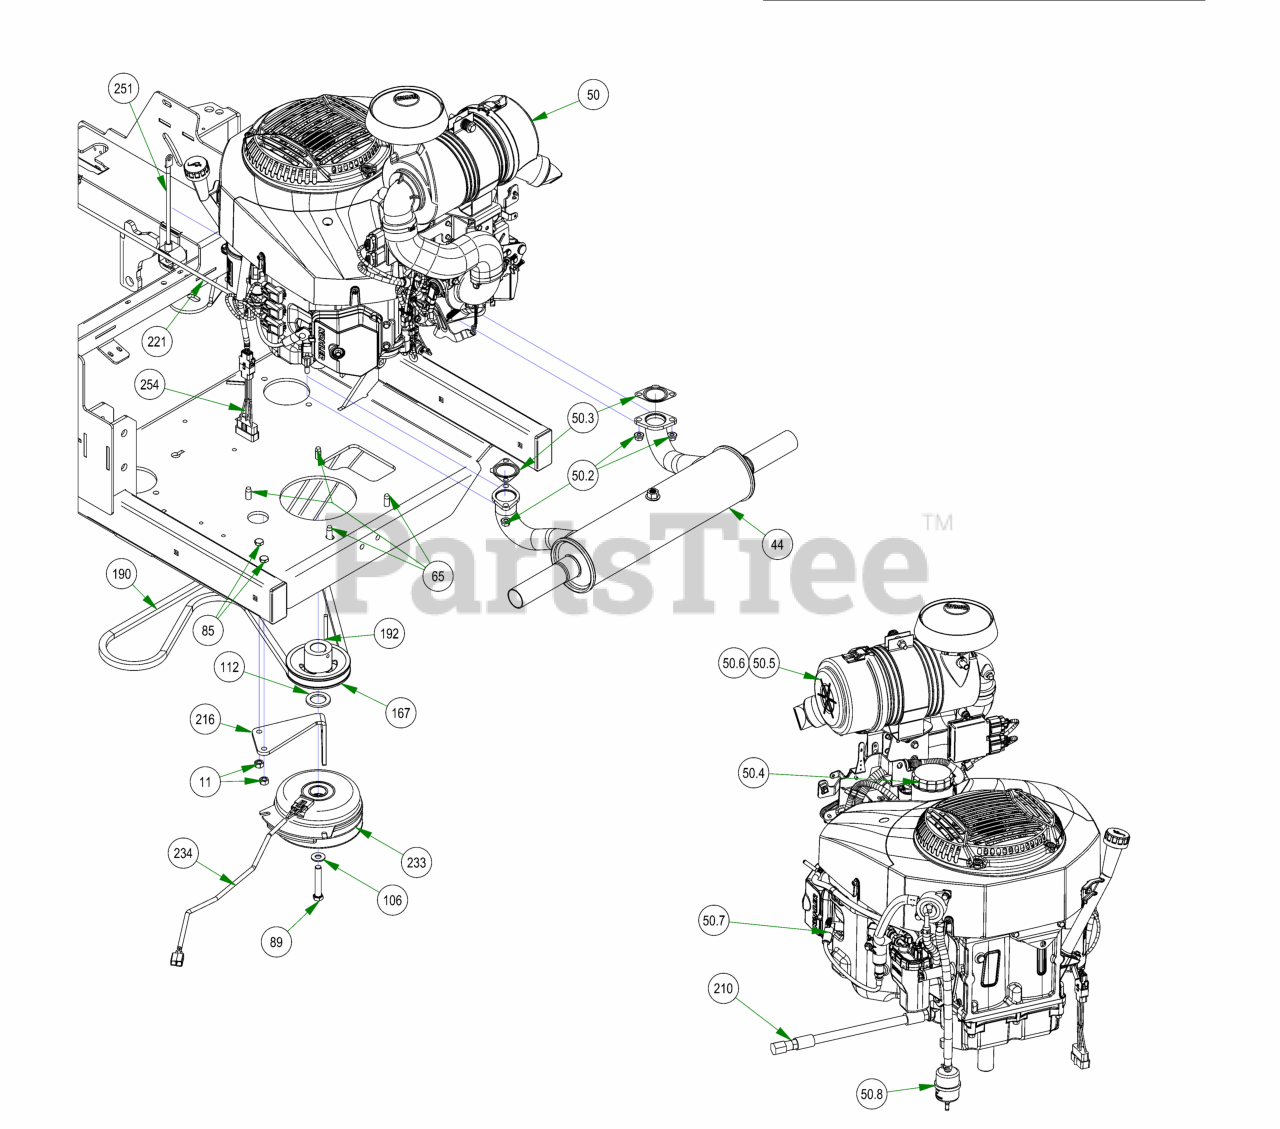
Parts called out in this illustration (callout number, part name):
11	3/8-16 HEX NUT ZINC
32	1 1/2 x 3 Frame Plug
44	2022 Kohler ECV-980 EFI Exhaust
50	KOHLER ECV-980 ENGINE
50.2	M8 Nut Connects the 015-1012-00 and the 015-8240-00
50.3	ECV/ECH 980 MUFFLER GASKET
50.4	Kohler ECV980
50.5	Canister Air Filter- Inner
50.6	Canister Air Filter- Outer
50.7	Spark Plug - Kohler ECV/ECH 980
50.8	Universal Inline Fuel Filter
65	3/8-16 X 1-1/8HEX WASHER UNSLOT SERRATED (TRI-LOB) TRS
85	3/8-16 X 1-1/4 HEX CAP SCREW (GR.5) ZINC
89	7/16-20 X 2-1/2 HEX Bolt GR 8 W/ Patch
106	3/8 FLAT WASHER USS (1" OD) ZINC
112	1.140 ID X 1.750 OD X .132 THICK FLAT WASHER PLAIN
167	4 3/4 Motor Pulley
190	2019 Rogue Pump Belt 68"
192	1/4 X 2 SQ MACHINERY KEY 1018 STL PLAIN
210	ECV/ECH 980 Oil Drain
216	PTO Engager Holder
221	24" Red Battery Cable
233	Clutch Assembly
234	Clutch Pigtail
235	2023 Rogue Frame - Painted
251	Starter Cable
254	2019 Harness Adaptor - Vanguard 37 EFI Vert/Horiz
